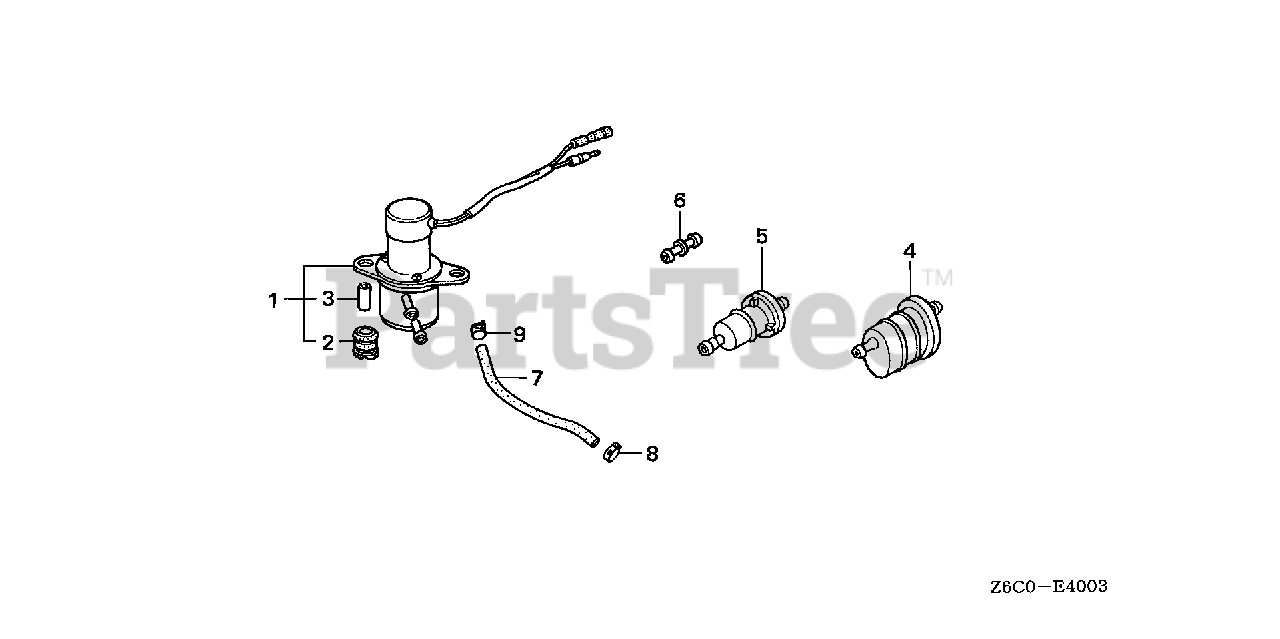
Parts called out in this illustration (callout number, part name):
1	PUMP ASSY., FUEL
2	RUBBER, FUEL PUMP SETTING
3	COLLAR, FUEL PUMP DISTANCE
4	FILTER, FUEL
